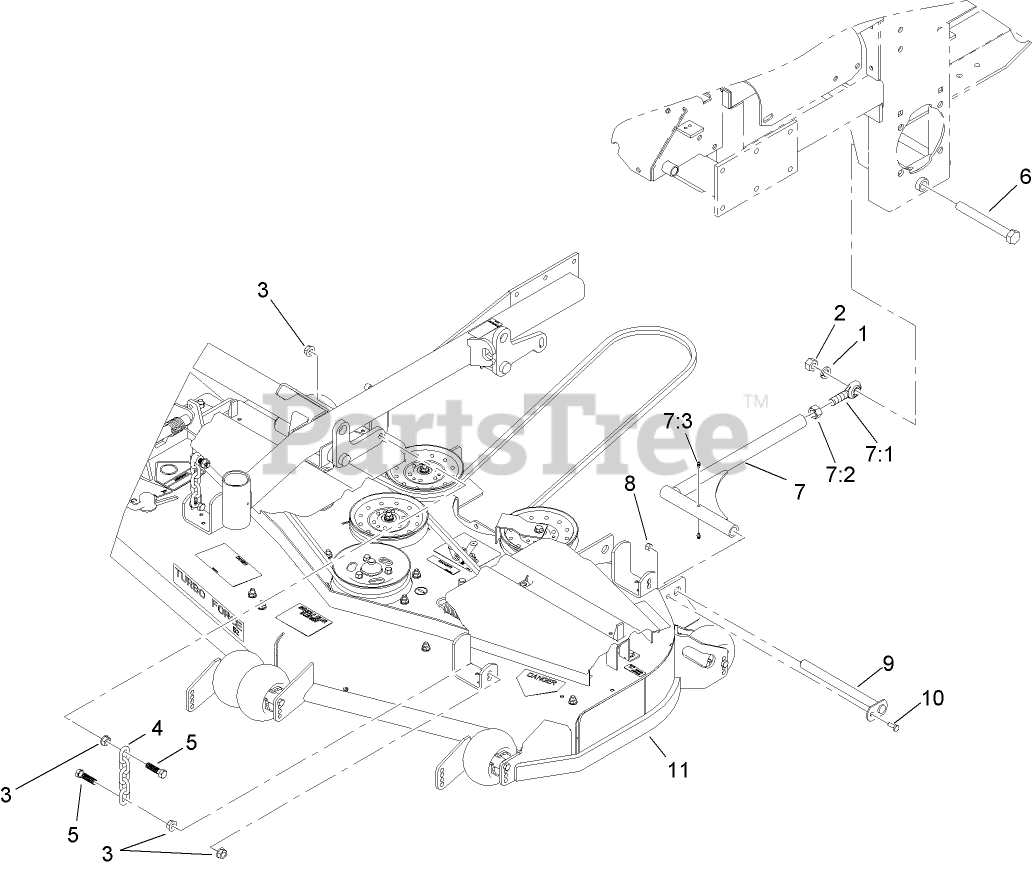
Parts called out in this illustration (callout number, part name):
1	WASHER-LOCK
2	NUT-HEX
3	NUT-HF
4	CHAIN-LIFT, DECK
5	SCREW-HH
6	SCREW-HH
7	STRUT ASM
7:1	BALLJOINT-SPHERICAL
7:2	NUT-HEX
7:3	FITTING-GREASE
8	NUT-LOCK, NI
9	PIN-STRUT
10	SCREW-HH
11	Deck ASM
